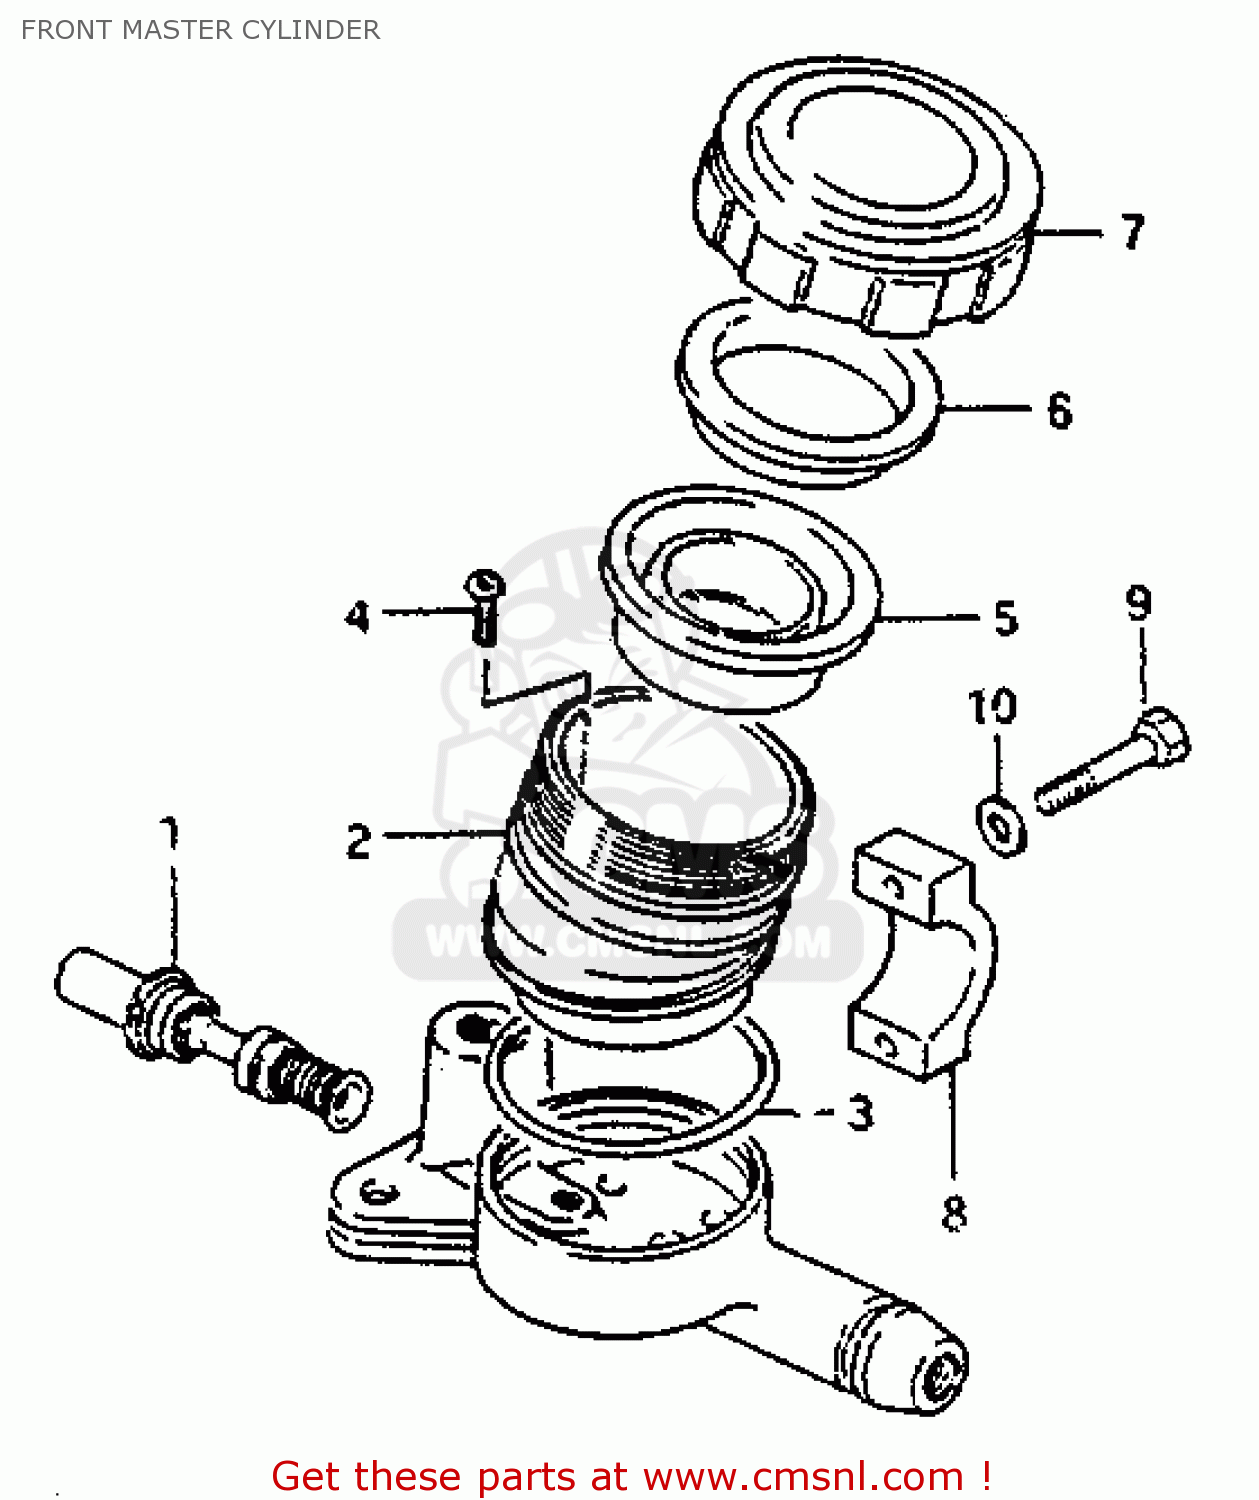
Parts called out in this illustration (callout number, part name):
1	PISTON & CUP SET
2	RESERVOIR
3	O RING
4	SCREW,MASTER CYLINDER
5	DIAPHRAGM
6	PLATE
7	CAP
8	HOLDER,MASTER CYLINDER
9	BOLT
10	WASHER
